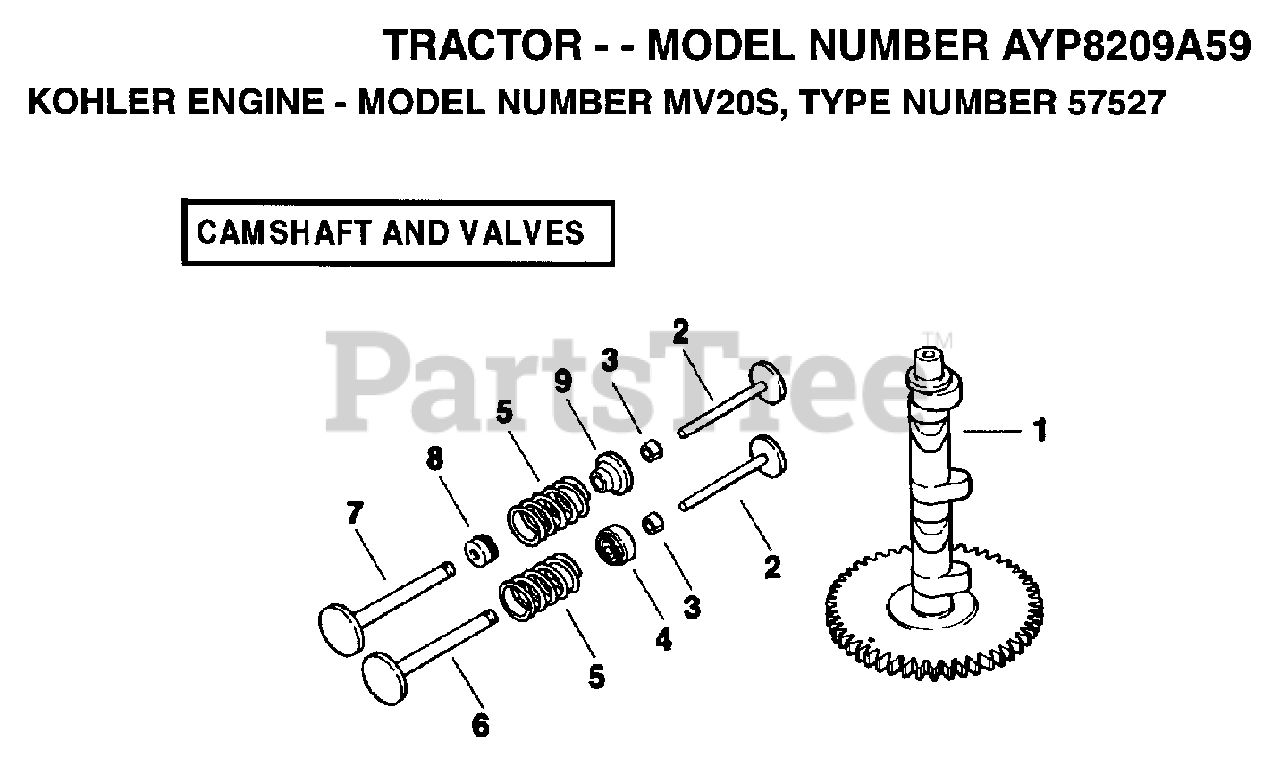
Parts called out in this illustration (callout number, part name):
6	VALVE EXHAUST
7	VALVE, INTAKE
9	RETAINER, INTAKE VALVE
